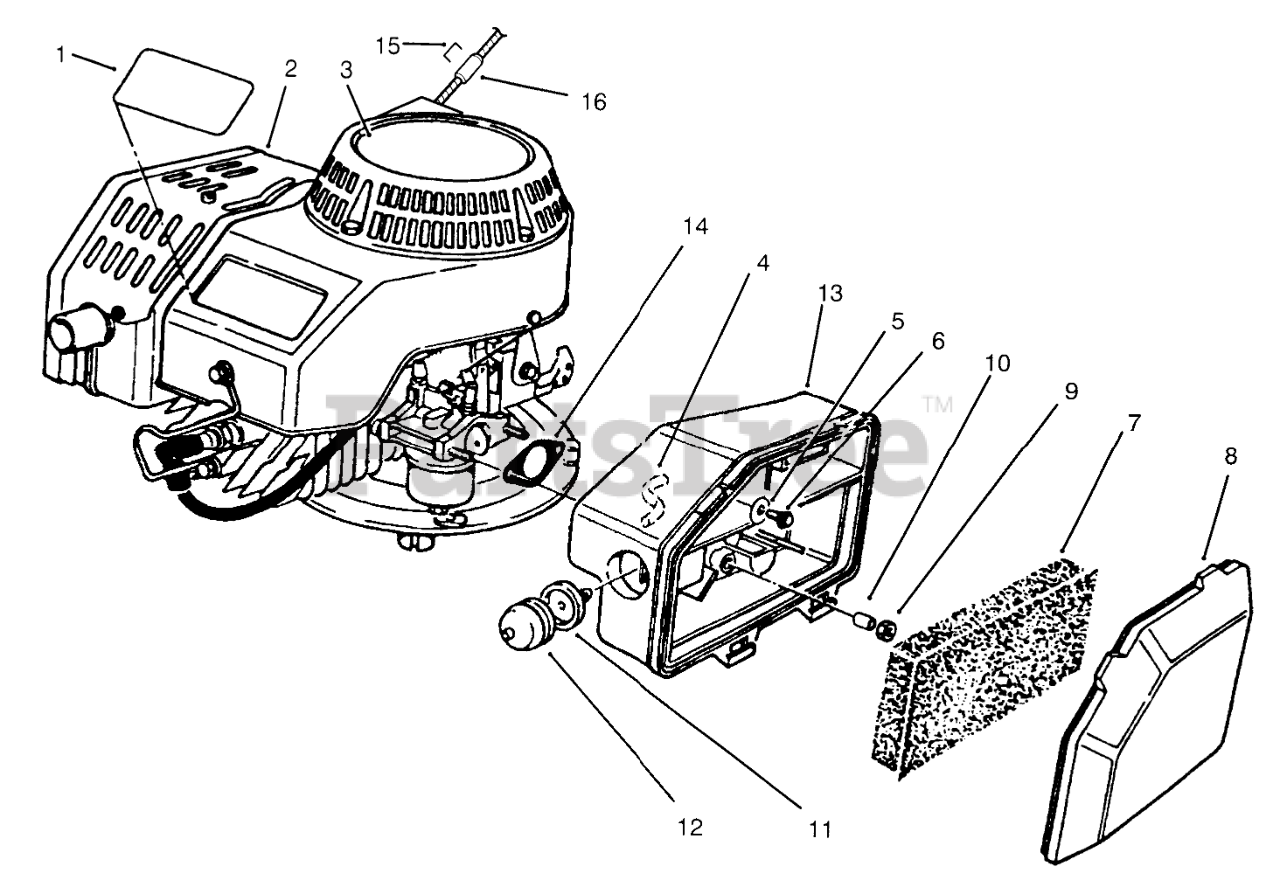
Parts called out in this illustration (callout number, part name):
1	DECAL - PROLINE
2	ENGINE ASM
3	DECAL-2 CYC RECOIL COMM
4	HOSE-PRIMER
5	WASHER-FLAT
6	SCREW-HH
7	ELEMENT-AIR CLEANER
8	COVER-AIR CLEANER
10	SPACER
11	BODY-PRIMER
12	BULB-PRIMER
13	BODY-AIR CLEANER
14	GASKET-AIR CLEANER
15	Staple
16	STOP-ROPE
